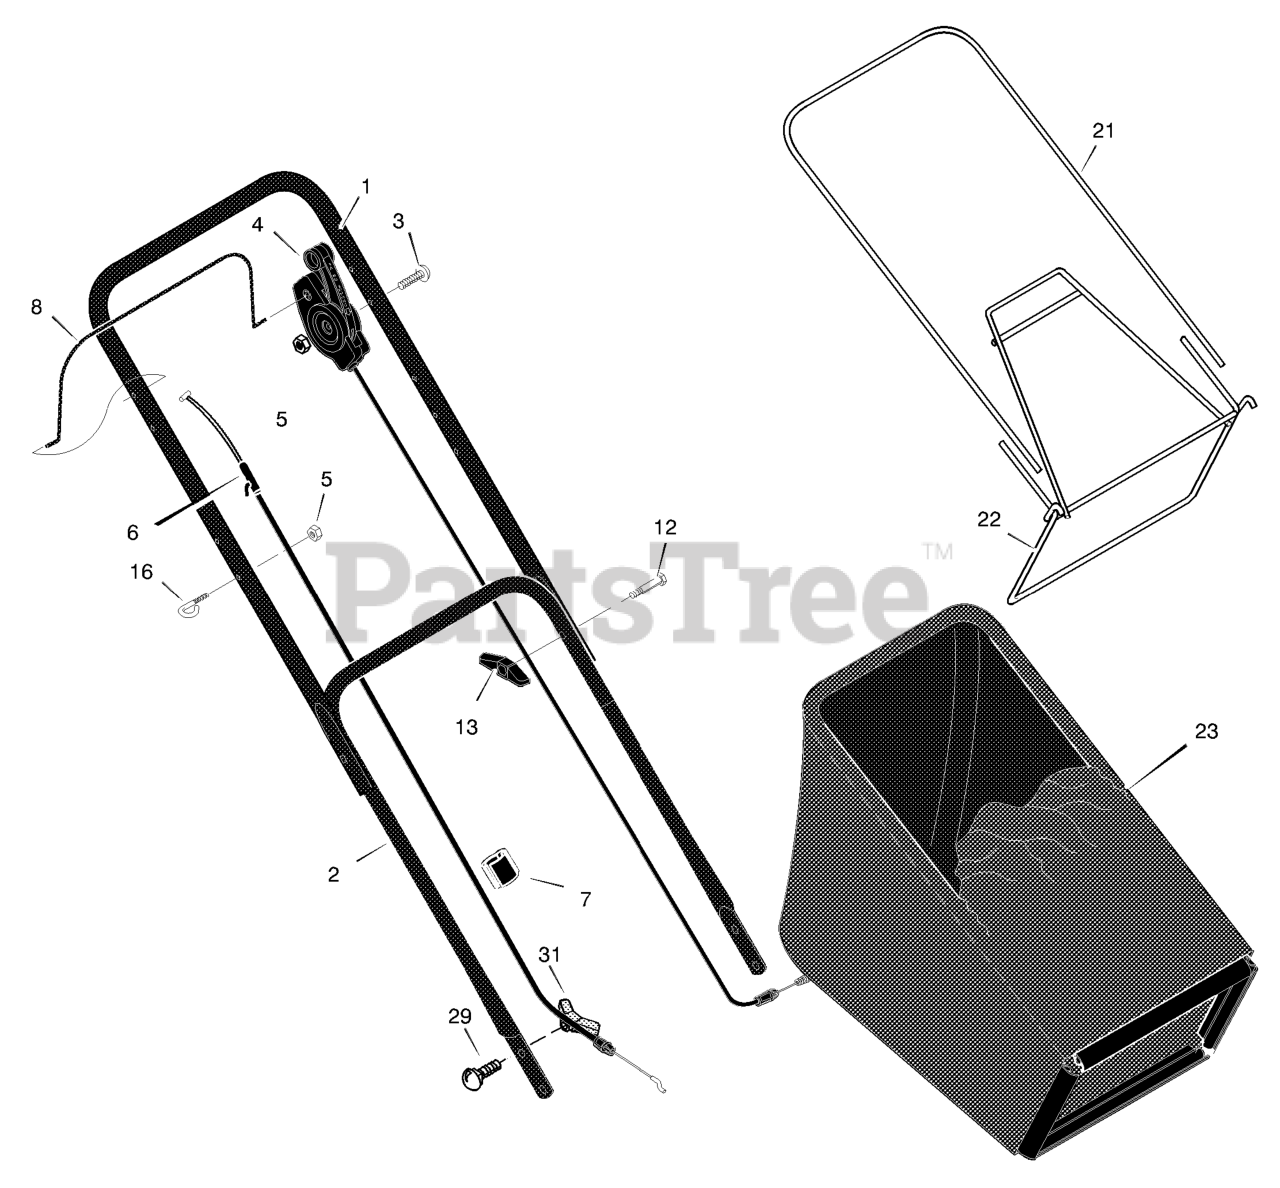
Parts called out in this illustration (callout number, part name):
1	Handle, Upper
2	Handle, Lower
4	Control, Drive
5	Locknut
6	Cable, Stop
7	Fastener, Single Cable
8	Lever, Stop
13	Knob
16	Guide, Rope
21	Frame, Top
22	Frame Assembly
23	Bag, Cloth
29	Bolt, Carriage
31	Knob, Plastic
